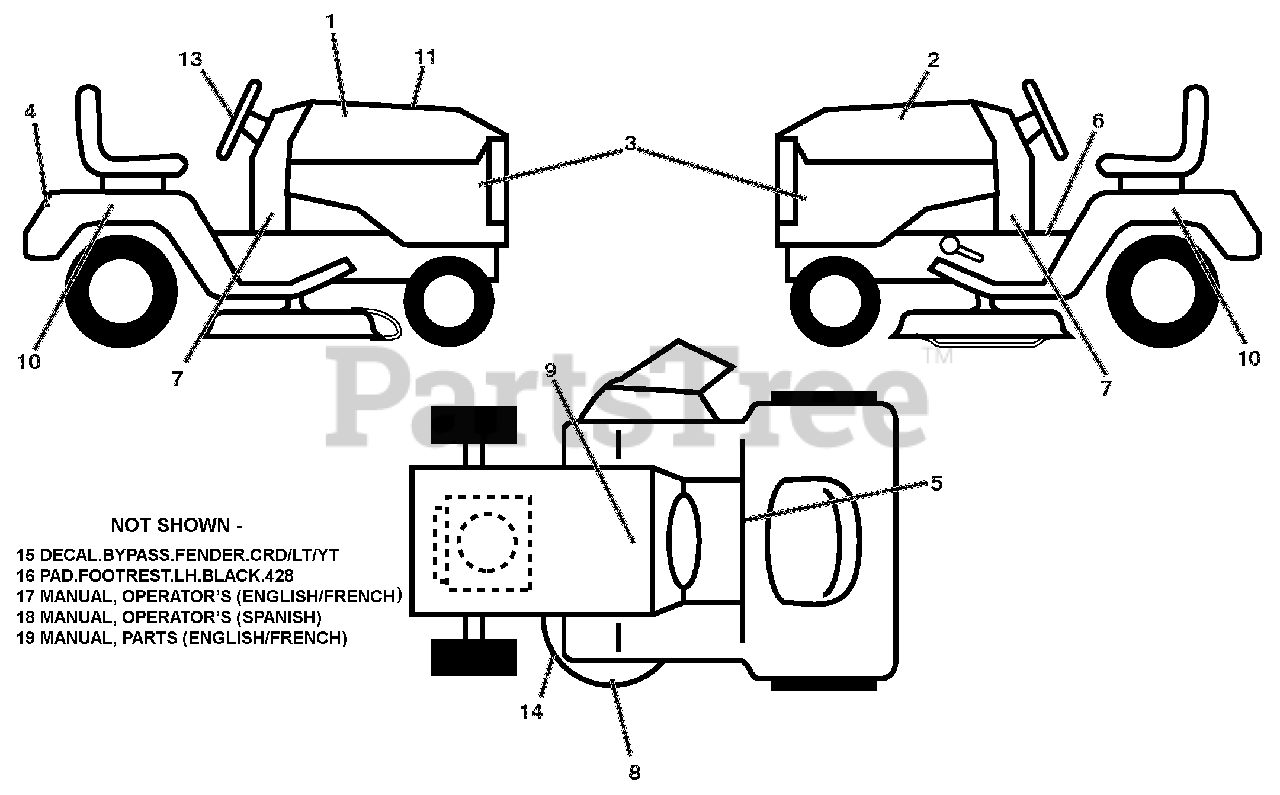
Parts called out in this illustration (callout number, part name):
1	DECAL.HOOD.RH.PRECISION.ARIENS
2	DECAL.HOOD.LH.PRECISION.ARIENS
3	DECAL.SDPNL.PWRDBY KOHL.ARIENS
4	Decal, Fender
5	Decal, Flag
6	DECAL, WARNING START INST.
7	DECAL.DASH.LOWER.
8	DECAL.MOWER.CAUTION.TENSION.AR
9	DECAL.BAT.DAN/POI P/L SYM.WPN
10	DECAL.FENDER.SIDE.HYDRO.ARIENS
11	DECAL, REPLACEMENT
13	DECAL.WHEEL.STEER.ARIENS
14	DECAL.V-BELT.SCH.42/46"MEC/ELE
15	DECAL.BYPASS.FENDER.CRD/LT/YT
16	PAD.FOOTREST.LH.BLACK.428
17	OWNER'S MANUAL, ENG/FRE
18	OWNER'S MANUAL, ENG/FRE
19	PARTS MANUAL
